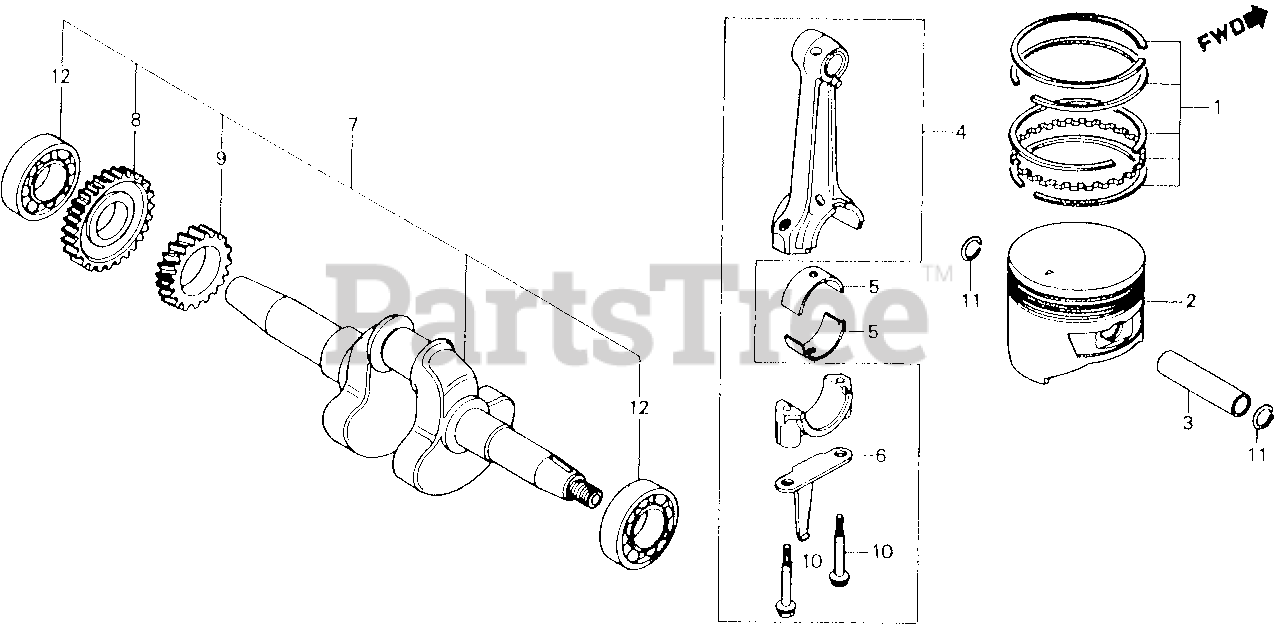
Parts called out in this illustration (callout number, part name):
1	RING SET, PISTON (STD)
1	RING SET, PISTON (STD) (NOT AVAILABLE)
1	RING SET, PISTON (OS 0.25)
1	RING, PISTON (OS 0.50)
1	RING SET, PISTON (OS 0.50)
1	RING SET, PISTON (0.75)
2	PISTON (STD) (NOT AVAILABLE)
2	PISTON (OS 0.25)
2	PISTON (OS 0.50)
2	PISTON (0.75)
3	PIN, PISTON
4	ROD ASSY., CONNECTING
5	BEARING A, CONNECTING ROD
5	BEARING B, CONNECTING ROD
5	BEARING C, CONNECTING ROD
5	BEARING D, CONNECTING ROD
5	BEARING E, CONNECTING ROD
6	DIPPER, CONNECTING ROD
7	CRANKSHAFT (NOT AVAILABLE)
8	GEAR, BALANCER
9	GEAR, TIMING
10	BOLT, CONNECTING ROD (8MM)
11	CLIP, PISTON PIN (19MM)
12	BEARING, RADIAL BALL (6206)
